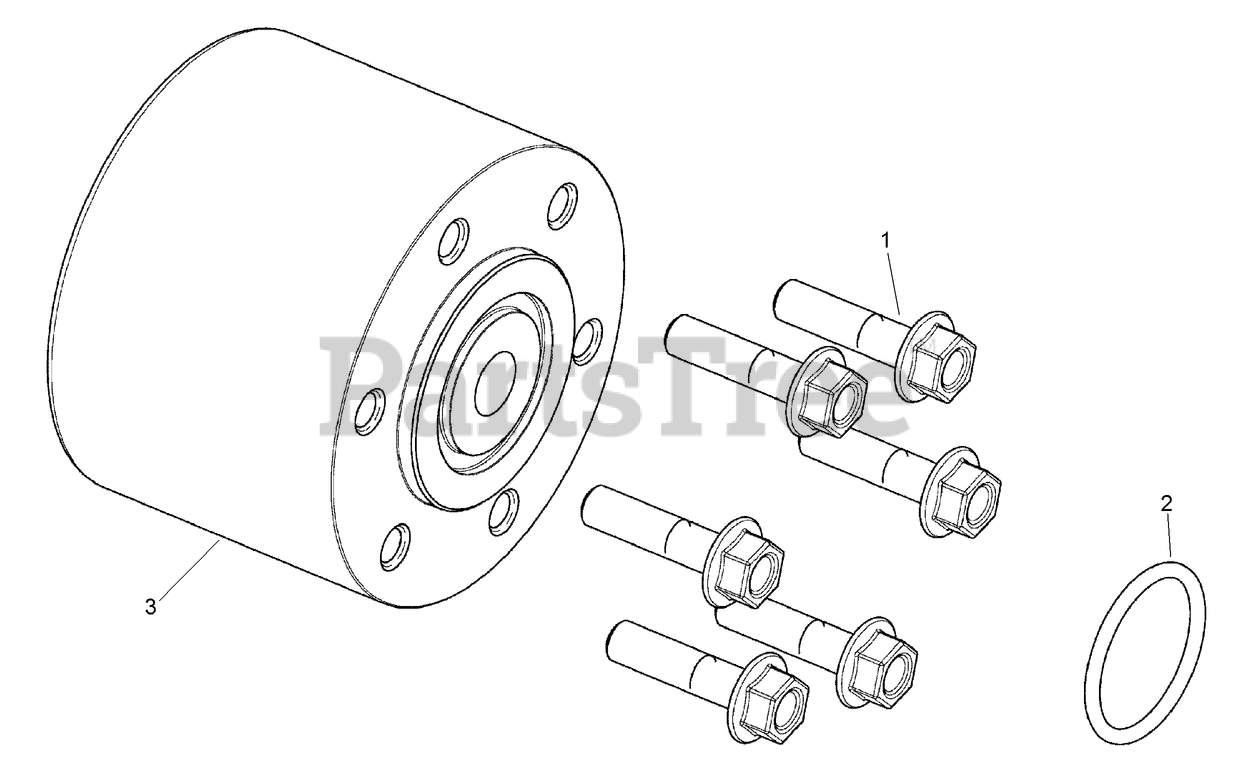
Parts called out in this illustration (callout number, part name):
1	SCREW-HHF
2	O-RING - 0.139 x 1.484 in
3	ADAPTER-SPINDLE
